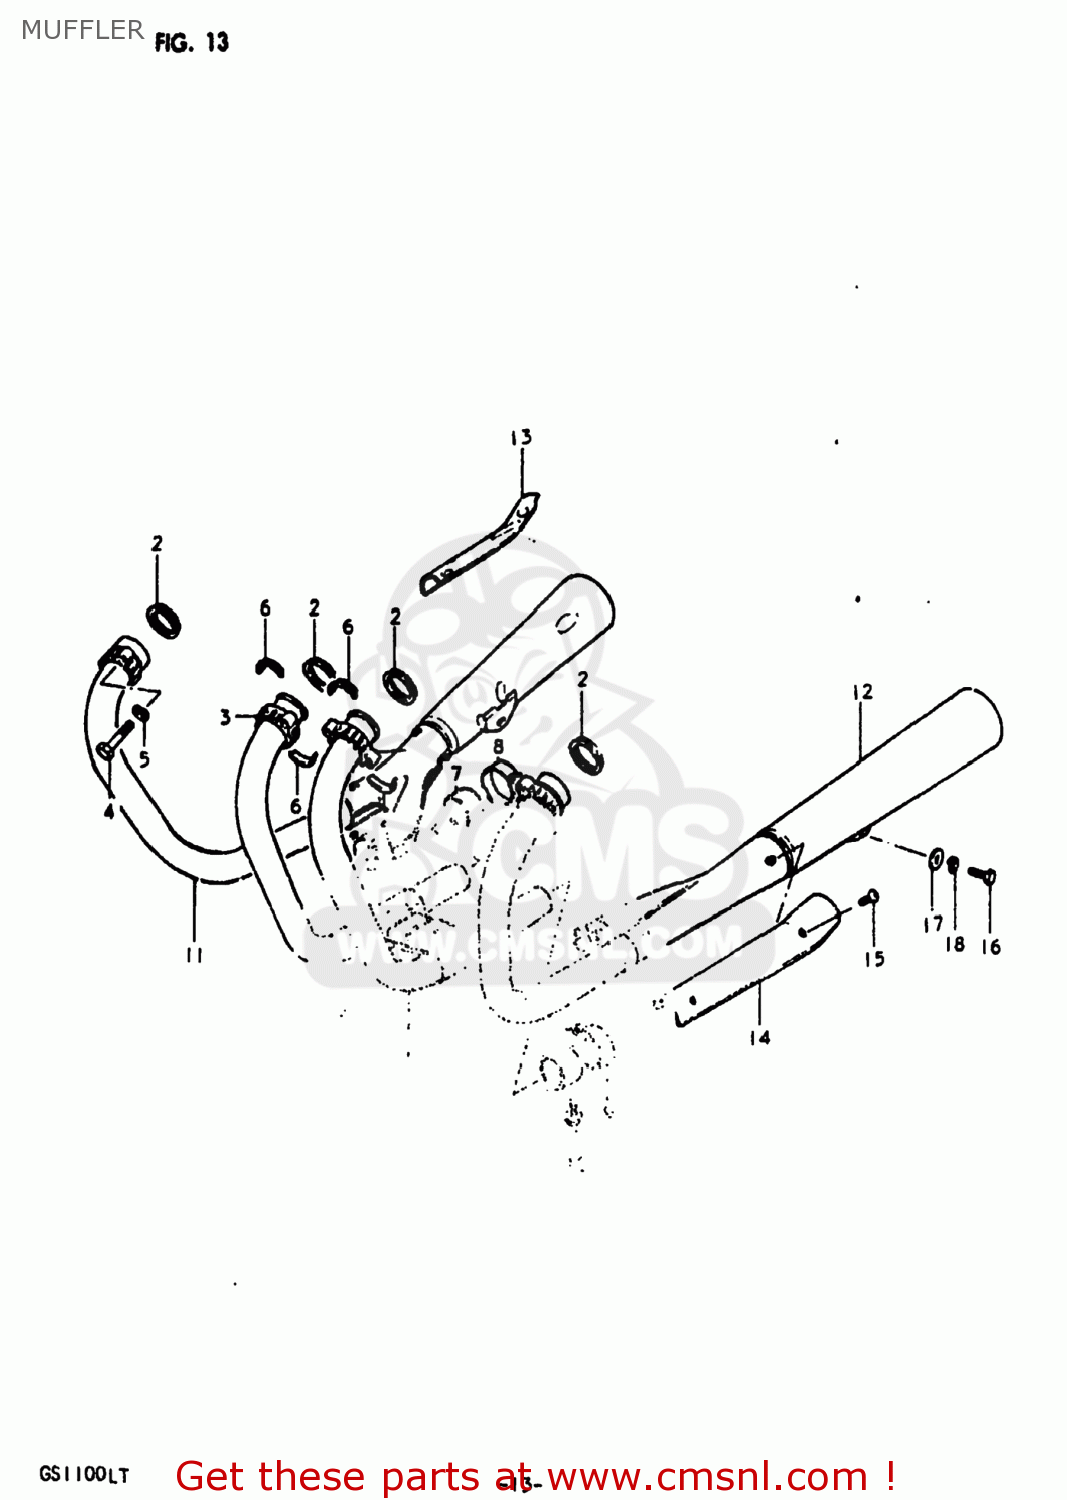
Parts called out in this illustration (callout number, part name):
1	PIPE,EXHAUST,CENTER
2	GASKET,EXHAUST PIPE (NAS)
3	CLAMP,EXHAUST PIPE
4	BOLT
5	LOCK WASHER
6	PLATE,EXHAUST
7	CONNECTOR,MUFFLER
8	CLAMP,MUFFLER CONNECTOR,R
9	CLAMP,MUFFLER CONNECTOR,L
10	BOLT
11	BODY,MUFFLER
12	BODY,MUFFLER
13	COVER,MUFFLER,RIGHT
14	COVER,MUFFLER,LEFT
15	SCREW
16	BOLT 10X30
17	WASHER
18	LOCK WASHER
